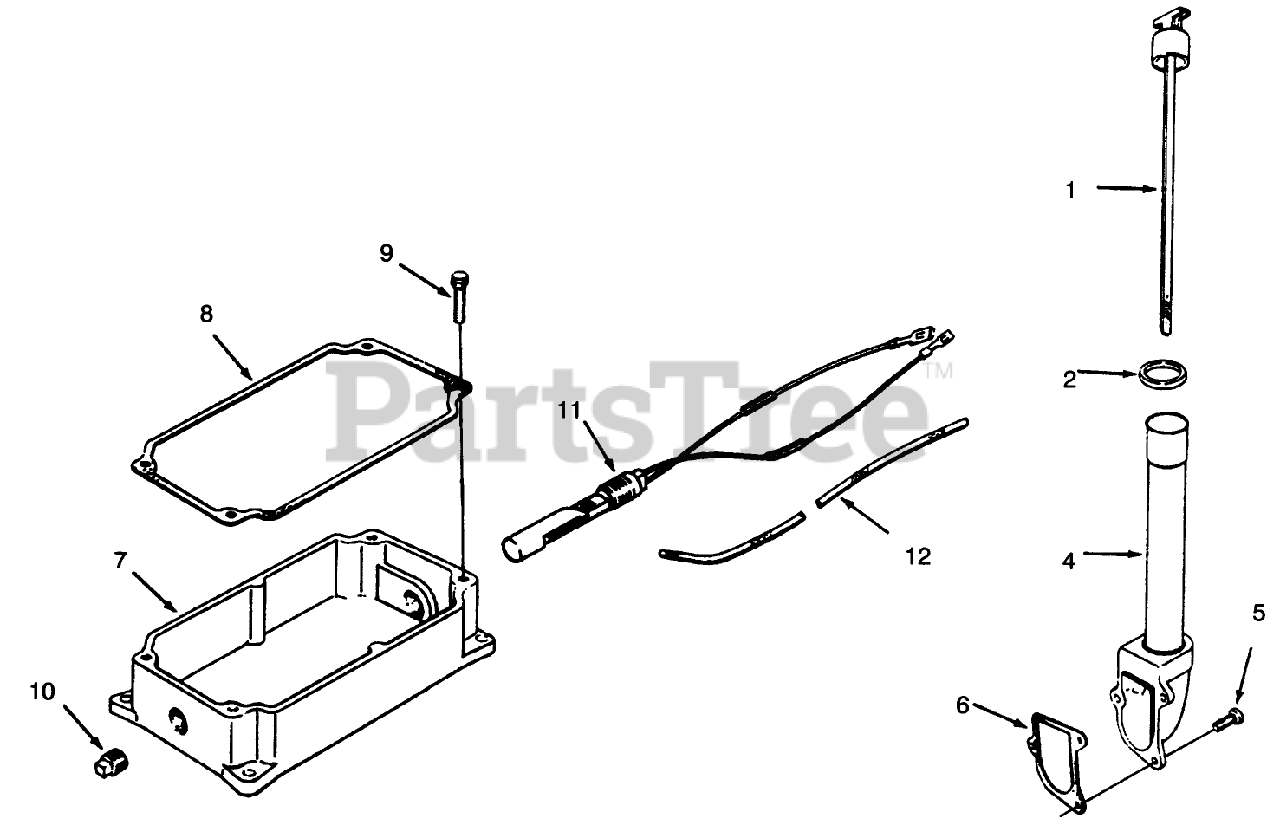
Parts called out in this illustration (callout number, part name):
1	KOHLER 47-038-27
2	KOHLER 41-153-01
4	KOHLER 47-029-06
5	KOHLER X-131-2
6	KOHLER 237064
7	KOHLER 45-199-05
8	KOHLER 235057
9	KOHLER X-159-3
10	KOHLER X-75-10
11	KOHLER 47-099-04
12	KOHLER 25-431-02
